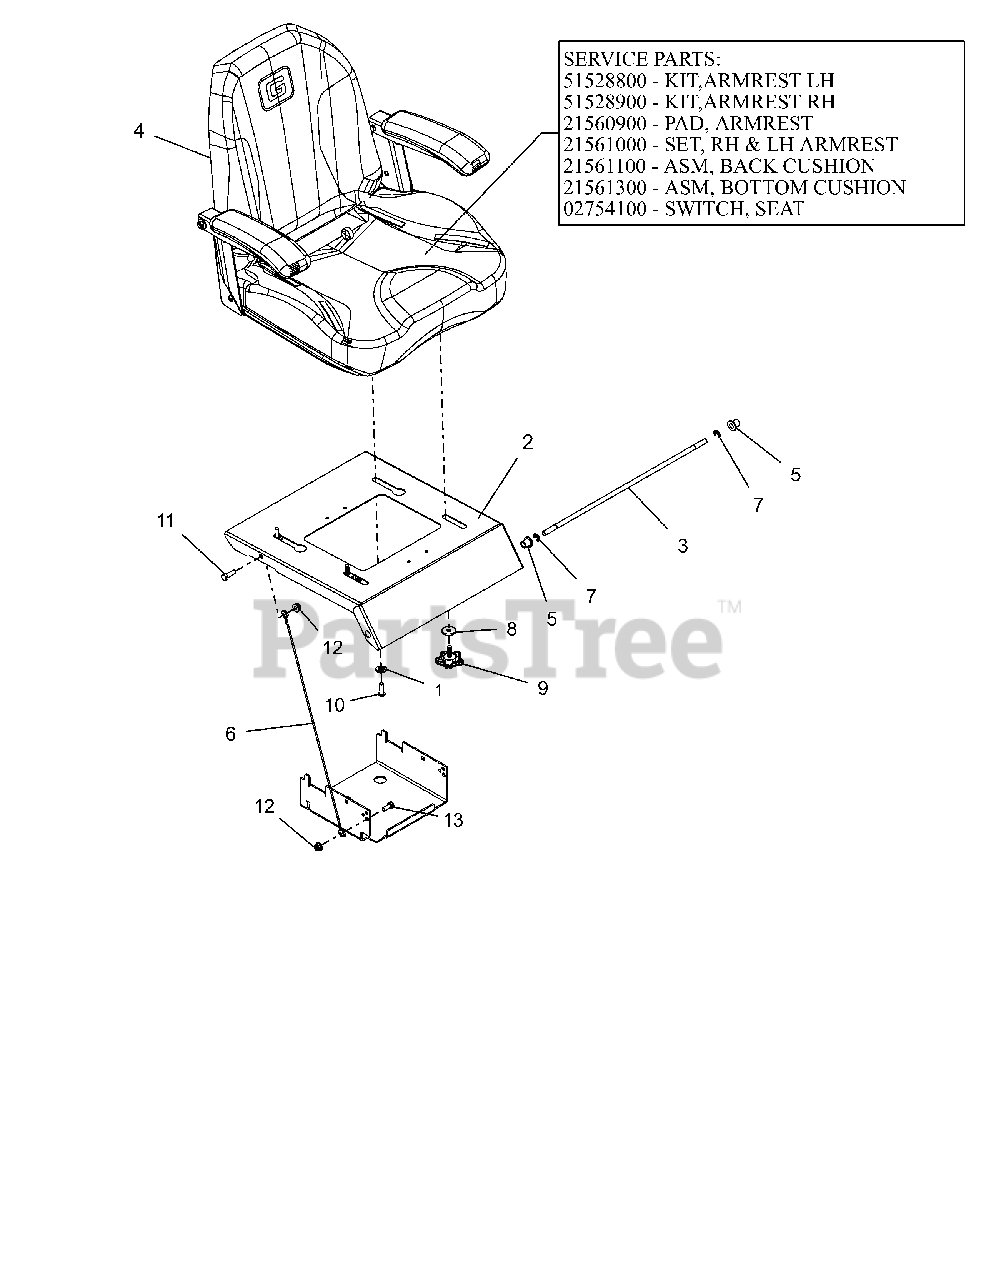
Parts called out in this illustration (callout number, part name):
1	BSHG, FLG .325X.499X.26X.88
2	PLATE, SEAT (FASTENER SLIDE)
3	ROD, SEAT PIVOT
4	SEAT, ZTX 2017
4	KIT, ARMREST LH
4	KIT, ARMREST RH
4	PAD, ARMREST (HARD)
4	SET,RH & LH ARMREST -HARD
4	ASM,BACK CUSHION-GRAVELY X
4	ASM,BOTTOM CUSHION-GRAVELY X
4	SWITCH- SNAP MTG N.O.
5	BSHG-FLG .38X.580X.667X.750
6	LANYARD, SEAT CABLE .093X19.5
7	RG-RTNG-EXT .375X.035 TYP E
8	WSHR, FLT .340X1.125X.135 ZCC
9	KNOB, WING STUDDED
10	BLT,SHCS-BTN .31-18X1.00 ZCC
11	BLT,HEX .31-18X1.00 G5 ZCC
12	NUT,NYL-FLG .31-18 GF ZCC
13	BLT,HEX .31-18X.75 G5 ZCC
